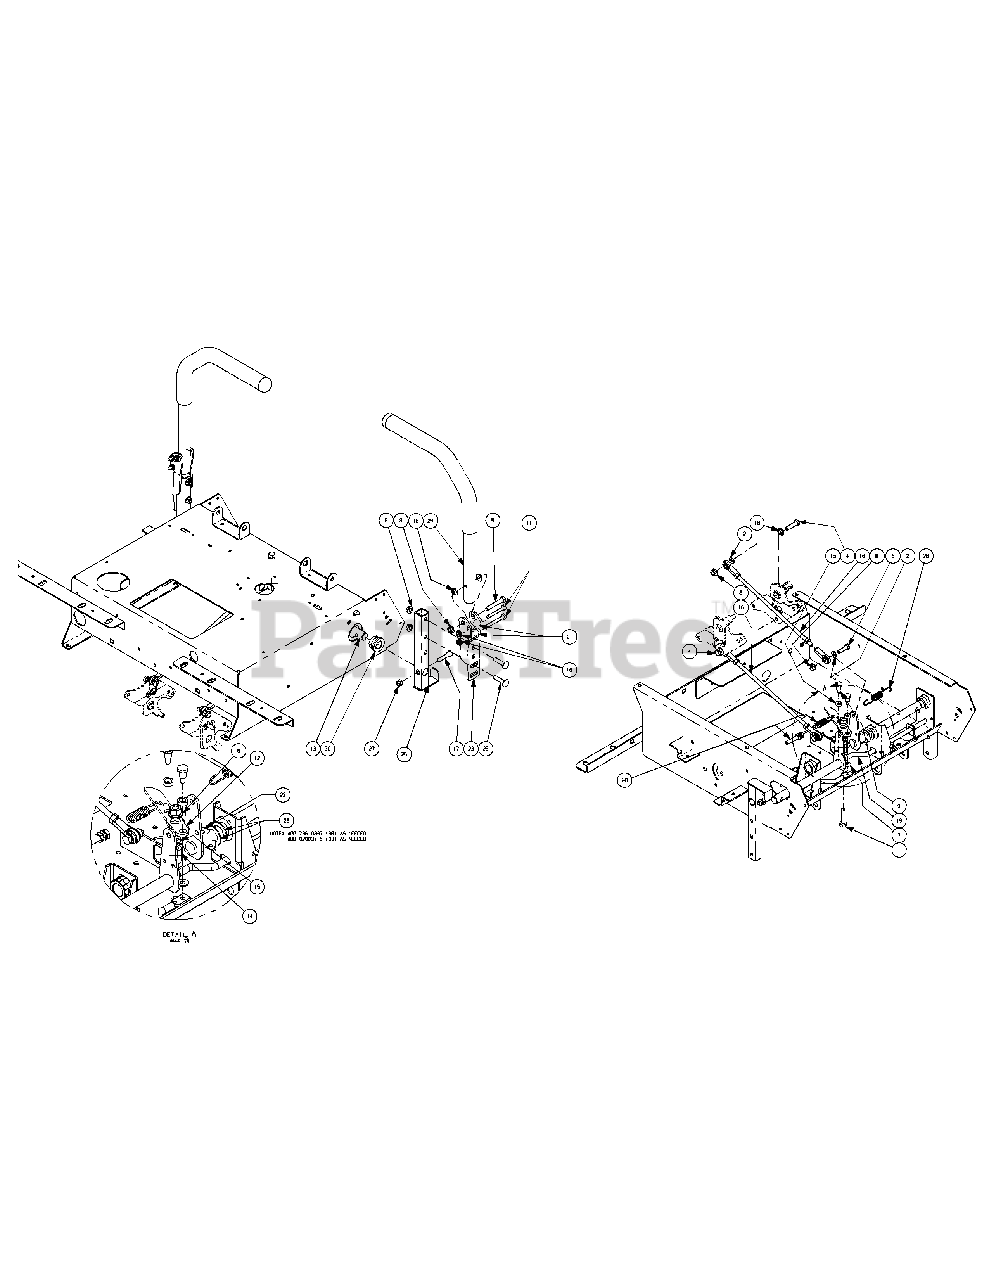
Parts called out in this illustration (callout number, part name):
1	Hex Cap Screw, 3/8-16 x 1-1/2
2	Flat Washer, 5/16
3	Hex Head Cap Screw, 5/16-18 x 1.00
4	HHCS, 5/16-18 x 1-1/4
5	Hex Cap Screw, 5/16-18 x 2.00
6	Nut, Flange Lock, 3/8-16
7	Flat Washer, 1.4 x .630 x .0515
8	Nut, 5/16-18, Lock
9	Shoulder Screw, 1/4-28
10	Nut, 1/4-20, Hex Flange Lock Nut
11	Hex Cap Screw, 1/4-20 x 2.00
12	Brake Lever Plate
13	Steering Input Shaft Assembly
14	Spacer, .385 ID x .625 OD x .869
15	Spacer, .380 x .563 x .196
16	Steering Link Rod
17	Socket Head Capscrew, 5/16-18 x 1.25
18	Bushing, .310 x .172 x .688 x .06
19	Control Lock Rod
20	Control Cable Lock Out
21	Spacer, .25 ID x .38 OD x 1.13
22	Retainer Ring, E-Clip
26	Carriage Bolt, 5/16-18 x 1.50
27	Nylock Nut, 5/16-18
28	Extension Spring, .544 OD x 3.35
29	Flat Washer, .793 ID x 1.24 OD x .060
30	Hex Flange Bearing, .752 ID
